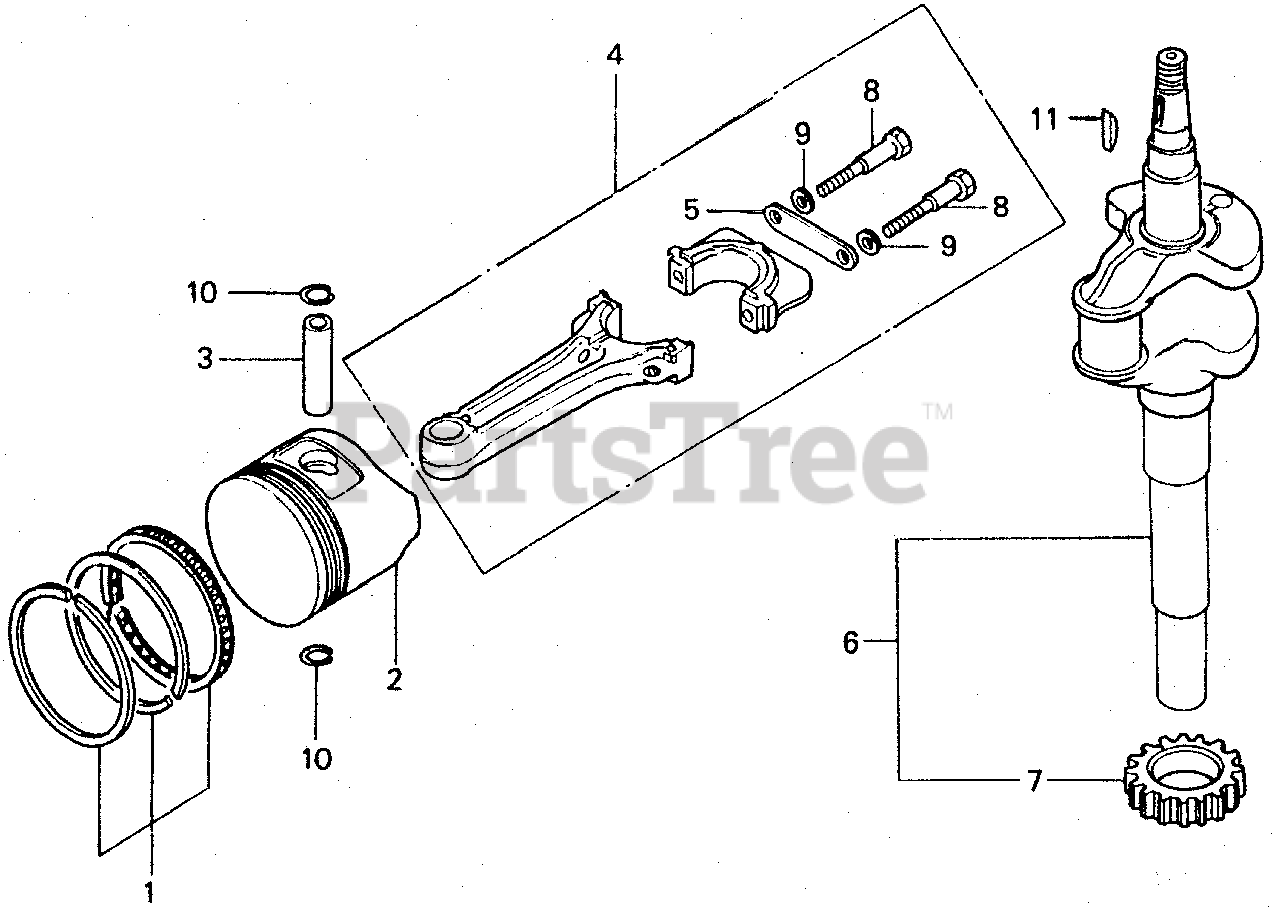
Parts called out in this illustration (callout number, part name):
1	RING SET, PISTON (STD)
1	RING SET, PISTON (0.25) (NOT AVAILABLE)
1	RING SET, PISTON (0.50) (NOT AVAILABLE)
1	RING SET, PISTON (0.75) (NOT AVAILABLE)
2	PISTON (STD)
2	PISTON (0.25)
2	PISTON (0.50)
2	PISTON (0.75) (NOT AVAILABLE)
3	PIN, PISTON
4	ROD ASSY., CONNECTING
4	ROD ASSY., CONNECTING (UNDER SIZE) (NOT AVAILABLE)
5	WASHER, CONNECTING ROD
6	CRANKSHAFT (NOT AVAILABLE)
7	GEAR, TIMING
8	BOLT, CONNECTING ROD (7MM)
9	WASHER, LOCK (7MM)
10	CLIP, PISTON PIN (15MM)
11	KEY, SPECIAL WOODRUFF (25X18)
